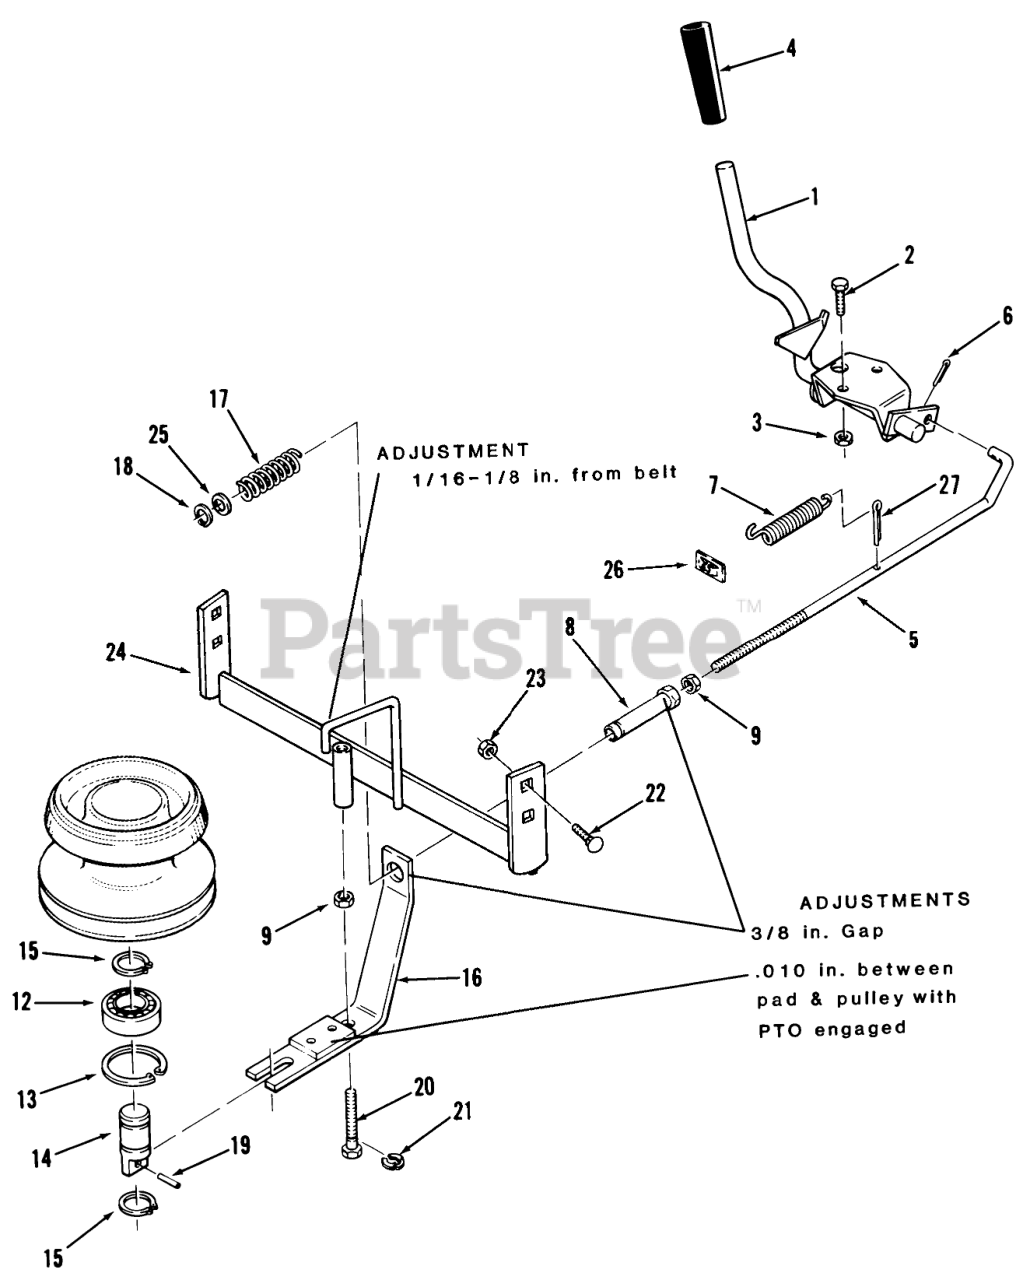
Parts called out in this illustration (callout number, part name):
1	ASSY-HANDLE
2	Bolt
3	Nut
4	GRIP
5	PTO Clutch Rod
6	Cotter Pin
7	Spring
8	TUBE-CLUTCH SPACER
9	Jam Nut 5/16-18
12	BEARING-BALL
13	Ring-Snap
14	Shaft Clutch Hsg
15	RING-SNAP, EXTERNAL
16	ASM-CLUTCH BRAKE PTO
17	SPRING-COMPRESSION
17	SPRING-CLUTCH
18	Retaining Ring
19	SPIROL PIN 7/32X7/8
20	SCREW-CLUTCH ADJUST
21	E-Ring
22	Bolt
23	Nut
24	Clutch Mounting Bracket 216-5 Only
24	Clutch Mounting Bracket
25	Washer
26	SPEED NUT
27	Pop Rivet
